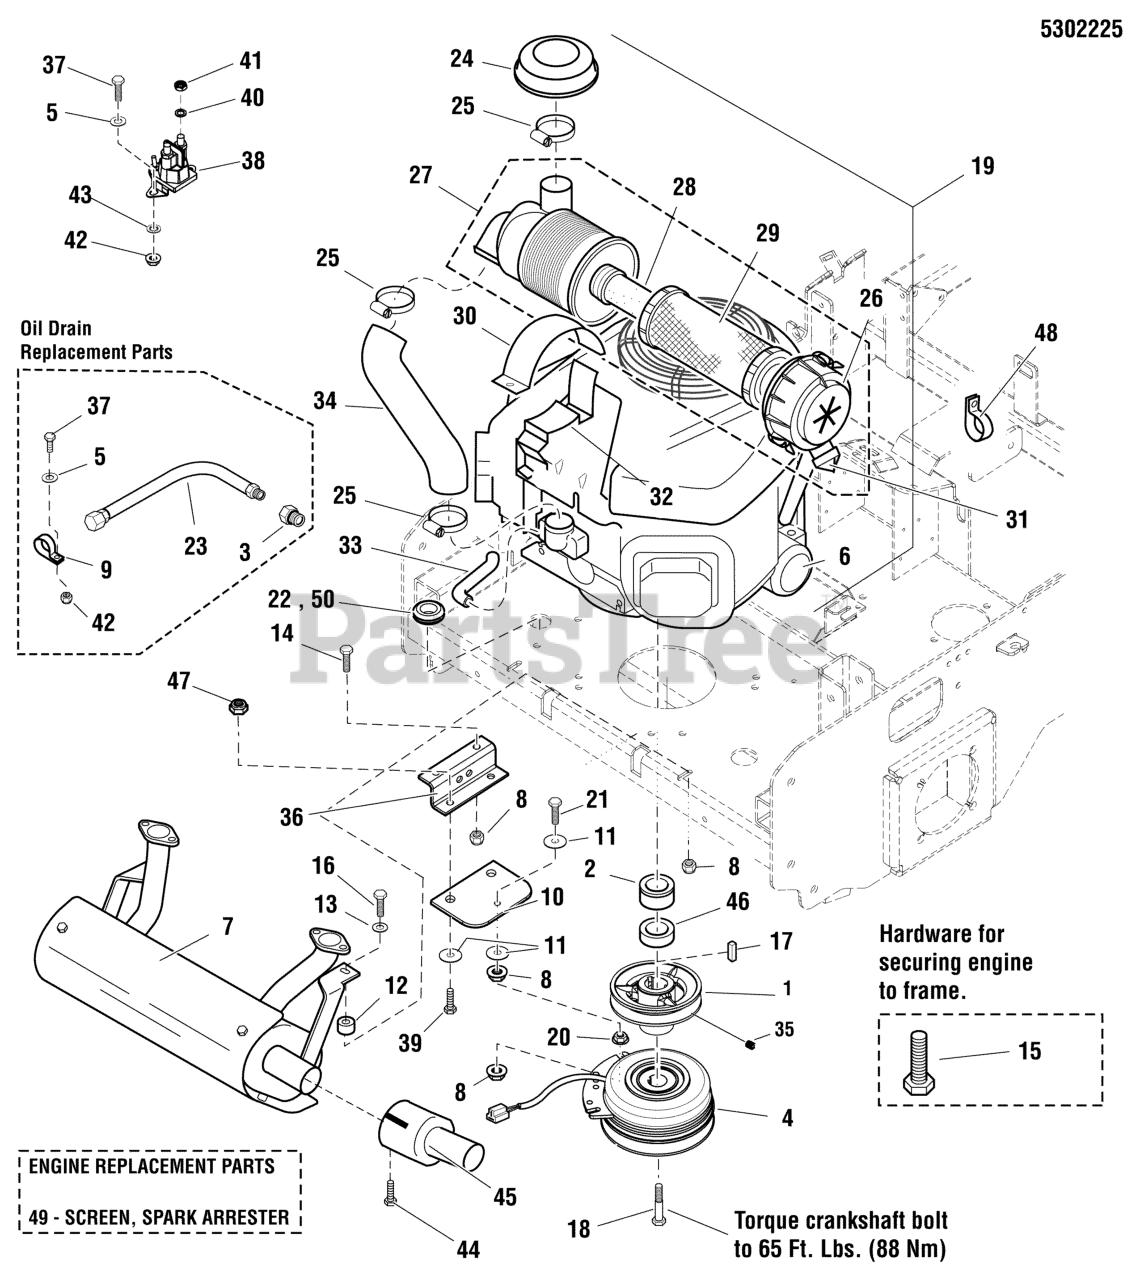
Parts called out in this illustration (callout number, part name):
1	PULLEY, 4.75 OD X 1-1/8 BORE, BC-48
2	SPACER, 1.13 X 1.75 X 1.03, CZ
3	HOSE, OIL DRAIN, M20 X 2.5
4	* CLUTCH, 5218-134, WARNER
5	WASHER, 1/4 SAE
6	OIL FILTER (49065-2078) (SV)
7	MUFFLER, KAWI, HORIZONTAL, 5" CAN
8	NUT, 5/16-18 HEX NYLOCK FLANGE
9	CLAMP, VINYL INSULATED
10	CLUTCH ANCHOR PAD
11	WASHER, .34 X 1.25 X 10 GA
12	SPACER, .39 X 1.00 X .80
13	WASHER, 5/16" SAE
14	BOLT, 5/16-18 X 1 GD5 YZ
15	BOLT,HEX FLG,SER GD5 3/8-16X1-1/4PACH CZ
16	BOLT, 5/16-18 X 1-3/4 GD5 YZ
17	KEY, 1/4 SQ X 1-1/4
18	BOLT, CRANKSHAFT, 7/16X2-3/4, PATCH YZ
19	* ENGINE, KAWASAKI
20	NUT, 5/16-18 HEX SERRATED FLANGE (LARGE)
21	BOLT, 5/16-18 X 2-1/4 TFL, GD5 YZ
22	GROMMET, 7/8
23	HOSE, OIL DRAIN
24	RAIN COVER (SV)
25	CLAMP (SV)
26	AIR FILTER CAP END (SV)
27	AIR FILTER ASSEMBLY, COMPLETE (SV)
28	AIR FILTER, SECONDARY (SV)
29	AIR FILTER, PRIMARY (SV)
30	CASE BRKT,AIR FILTER
31	RUBBER, DUST VALVE (SV)
32	CASE BRKT,AIR FILTER
33	BREATHER TUBE (SV)
34	AIR INLET TUBE (SV)
35	SET SCREW, 5/16-18 X 3/8, KNURL, W/PATCH
36	ANCHOR, CLUTCH - BLK
37	BOLT, 1/4-20 X 3/4 GD5 YZ
38	SOLENOID-4 POLE 12 VOLT DC (TROMBETTA)
39	BOLT, 5/16-18 X 1 GD5 YZ
40	WASHER, 5/16 LIGHT LOCK (SV)
41	NUT, 5/16-24 JAM (SV)
42	NUT, 1/4-20 HEX NYLOCK FLANGE
43	WASHER, 1/4 INTERNAL TOOTH LOCK
44	SCREW,SELF-TAP,#8-32 X 3/8,WASH HEX, CZ
45	EXTENSION, TAILPIPE, 3" - BLACK
46	SPACER, 1.13 X 1.75 X .25
47	NUT, 5/16-18 HEX NYLOCK FLANGE
48	CLAMP, HOSE, 1.000 DIA
50	GROMMET, 7/8"ID, 1/4" THICK STK
